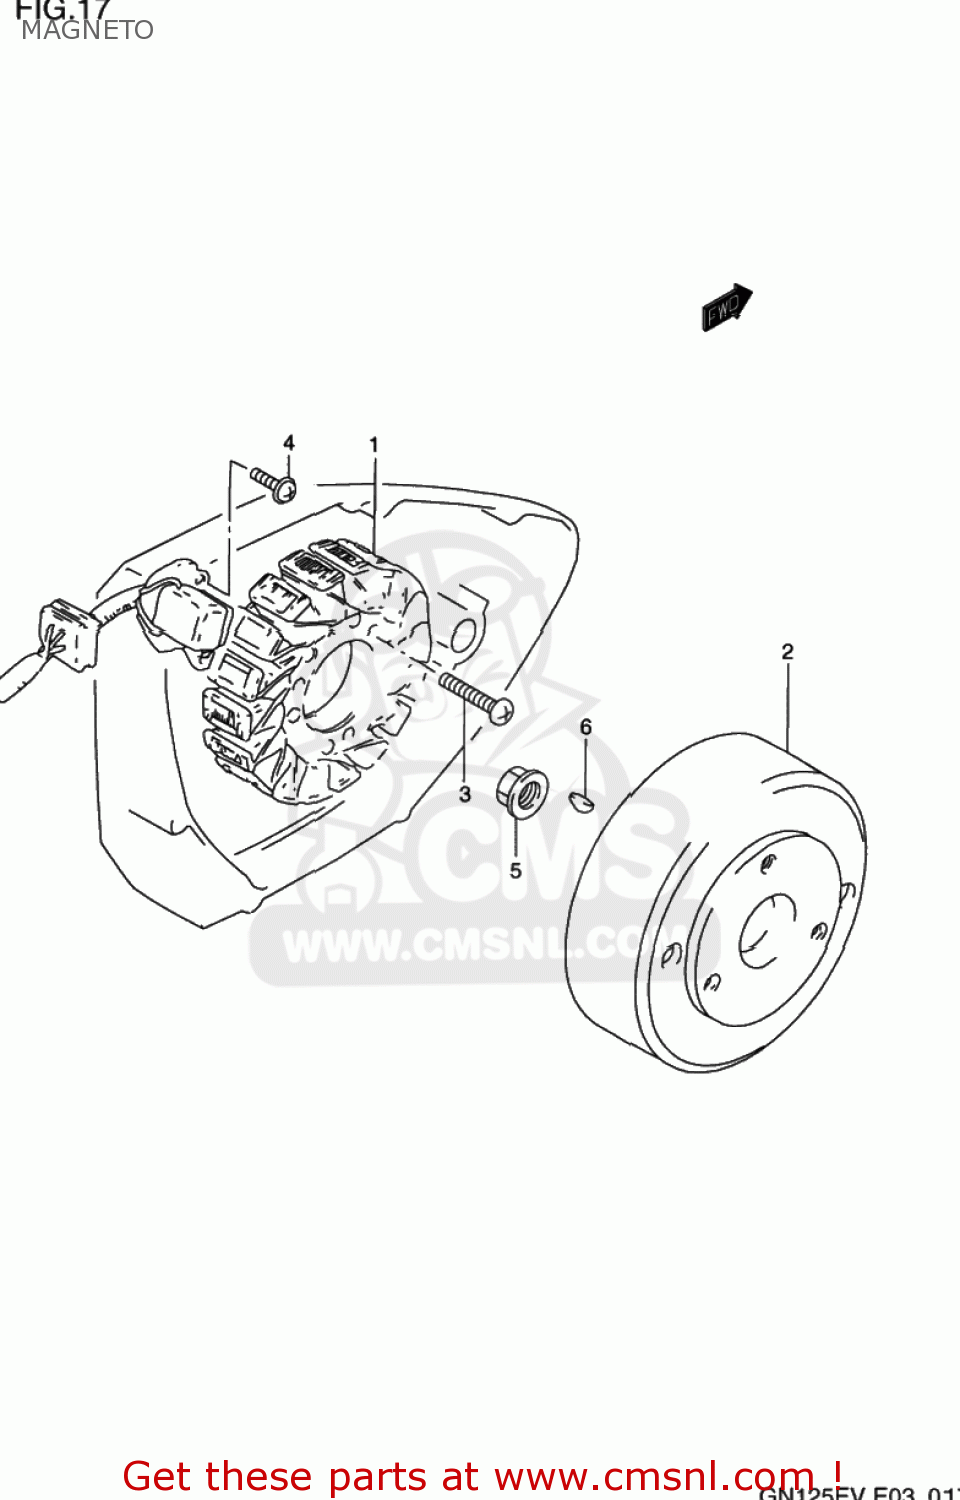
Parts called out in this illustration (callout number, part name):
1	STARTER ASSY
2	ROTOR,FLYWHEEL
3	SCREW
4	SCREW
5	NUT
6	KEY
